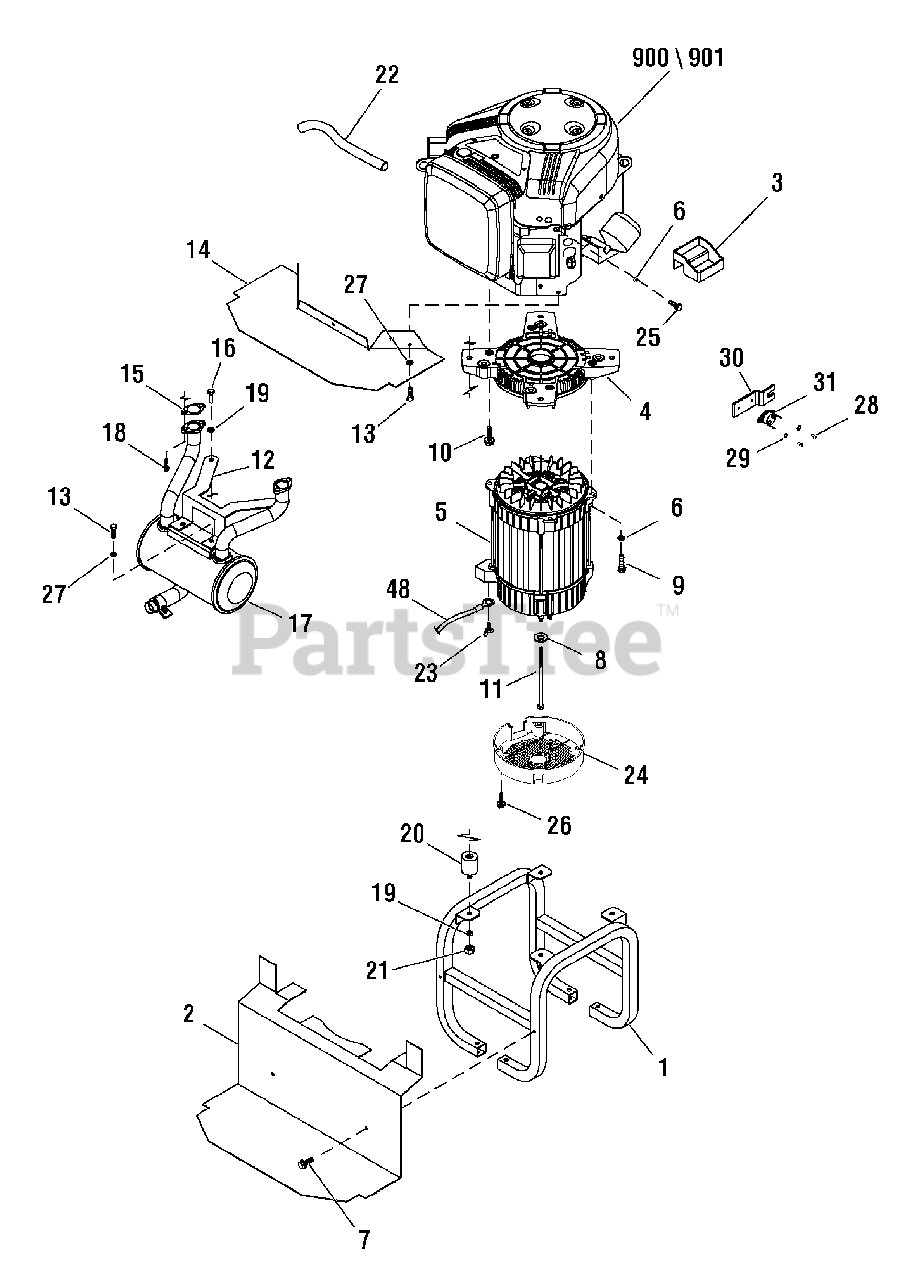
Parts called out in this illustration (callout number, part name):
2	BOX, Muffler Bottom
3	TRAY, Oil Drain
4	ADAPTER, Engine
5	ALTERNATOR
6	* WASHER, Lock, 5/16 - M8
7	BOLT
9	* CAPSCREW, Hex Head, 5/16-18 x 1
10	TAPTITE
12	BRACKET, Muffler
13	* CAPSCREW, Hex Head, M6 - 1 x 12
14	BOX, Muffler Top
16	* CAPSCREW, Hex Head, 3/8-16 x 1
19	* WASHER, Lock, 3/8
20	MOUNT, Vibration
21	* NUT, 3/8-16
22	HOSE, Oil Drain
24	COVER, Rear Bearing
25	* CAPSCREW, Hex Head, M8 - 18 x 1/2
27	* WASHER, Lock, 1/4
28	SCREW
900	** ENGINE
